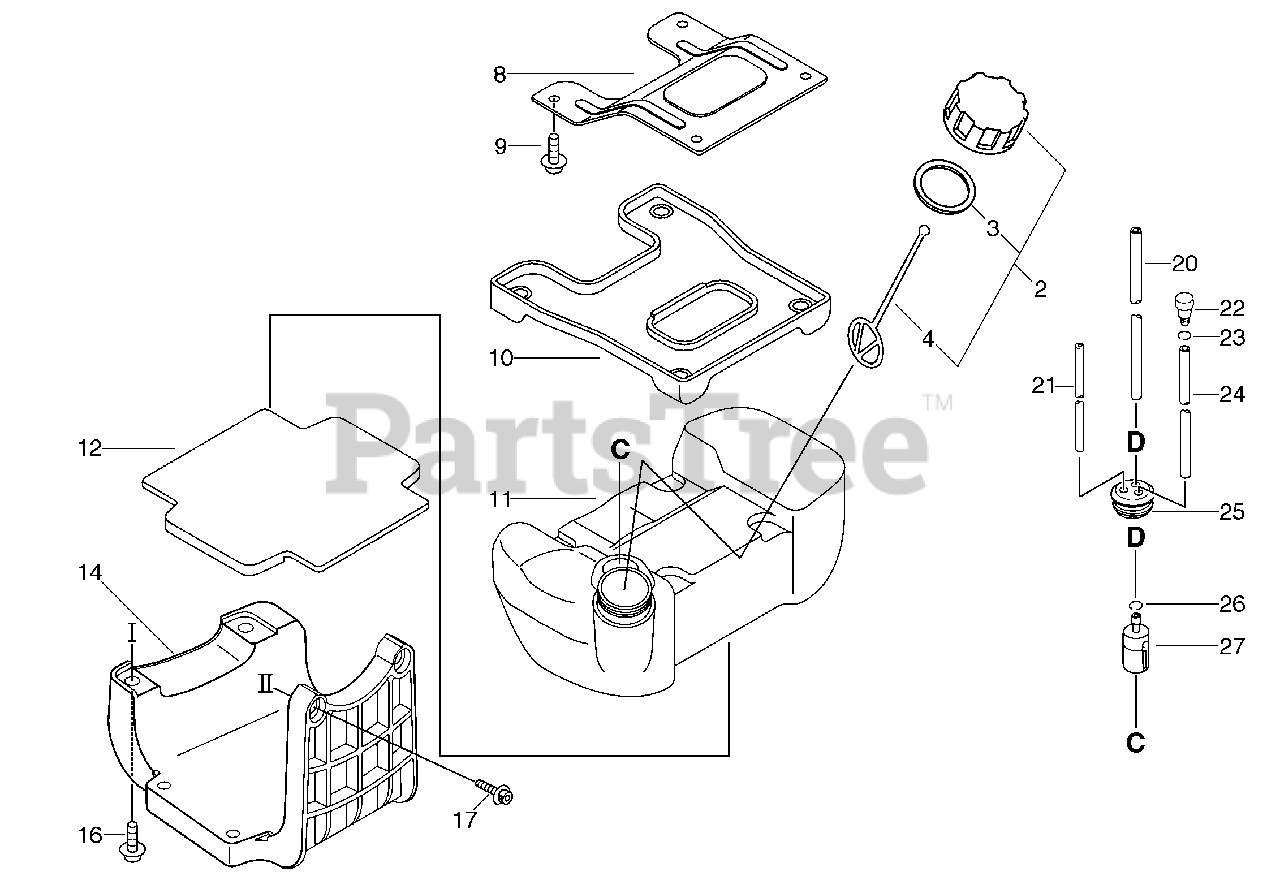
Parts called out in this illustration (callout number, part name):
2	CAP ASSY - ORANGE
3	GASKET, CAP
4	CONNECTOR, CAP
8	BRACKET, FUEL TANK
9	SCREW - 5X12
10	CUSHION, TANK - UPPER
11	TANK, FUEL
12	CUSHION, TANK - LOWER
14	BRACKET, FUEL TANK
16	SCREW - 5X20
17	SCREW - 5X25
20	PIPE - 3X6X180 -- BLACK
21	PIPE - 3X6X60 -- CLEAR
22	VENT, FUEL TANK
23	CLIP - 6.5
24	PIPE - 3X6X120 -- BLACK
25	GROMMET
26	CLIP - 6.5
27	FILTER, FUEL
